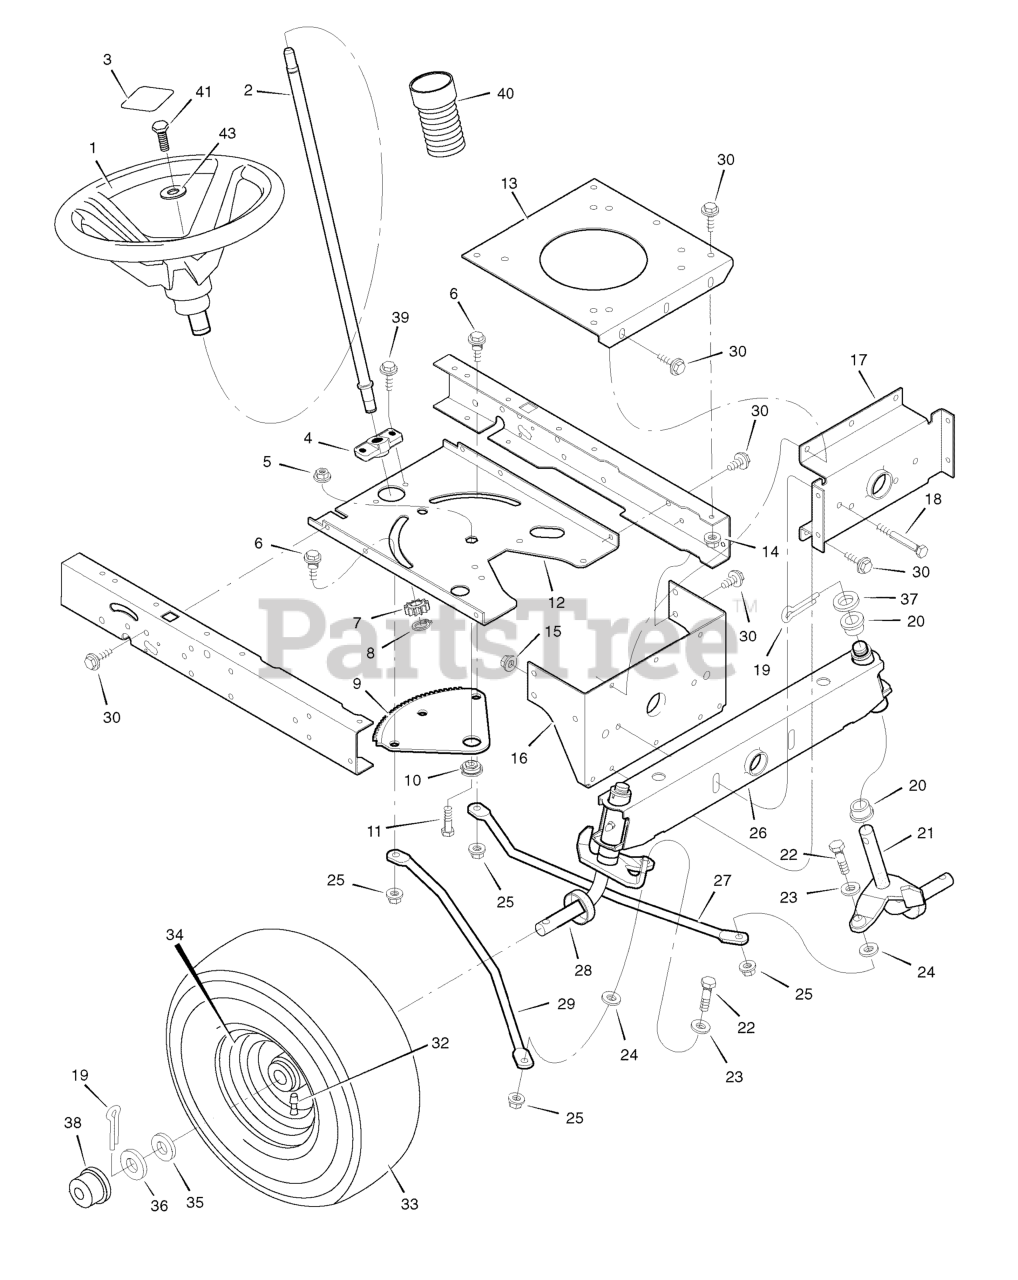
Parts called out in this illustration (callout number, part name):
1	WHEEL, Steering
2	POST, Steering
3	COVER, Steering Wheel
4	Bearing
5	Nut, Flange **
6	BOLT, Shoulder
7	GEAR, Pinion **
8	Ring, Snap **
9	GEAR, Sector
10	BEARING
11	BOLT
12	PLATE, Steering
13	PLATE, Engine
14	NUT, Flange
15	NUT, Flange
16	BRACKET, Hanger
17	AXLE, Hanger
19	PIN, Cotter
20	BEARING
21	SPINDLE ASSEMBLY, Left
22	BOLT
24	WASHER
25	NUT, Flange
26	AXLE ASSEMBLY
27	DRAG LINK, Left
28	SPINDLE ASSEMBLY, Right
29	DRAG LINK, Right
32	STEM, Valve
34	WHEEL & TIRE ASSEMBLY
38	HUB CAP
40	BELLOWS
41	Screw, Hex
43	WASHER
